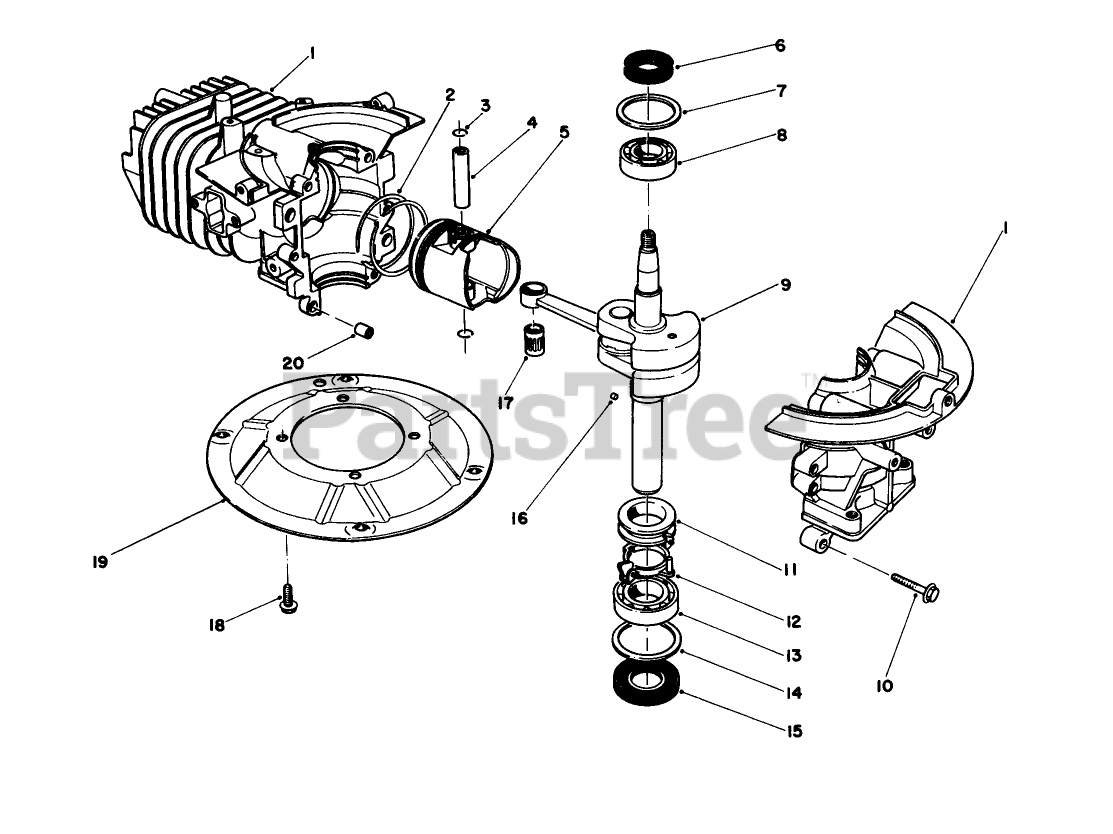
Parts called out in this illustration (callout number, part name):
2	RING SET
4	PIN-PISTON
6	OIL SEAL
7	WASHER-UPPER
8	BEARING-UPPER
11	SPACER
12	BRACKET
13	LOWER BRG
14	WASHER-LOWER
15	SEAL-OIL
17	BEARING
19	PLATE-MOUNTING
